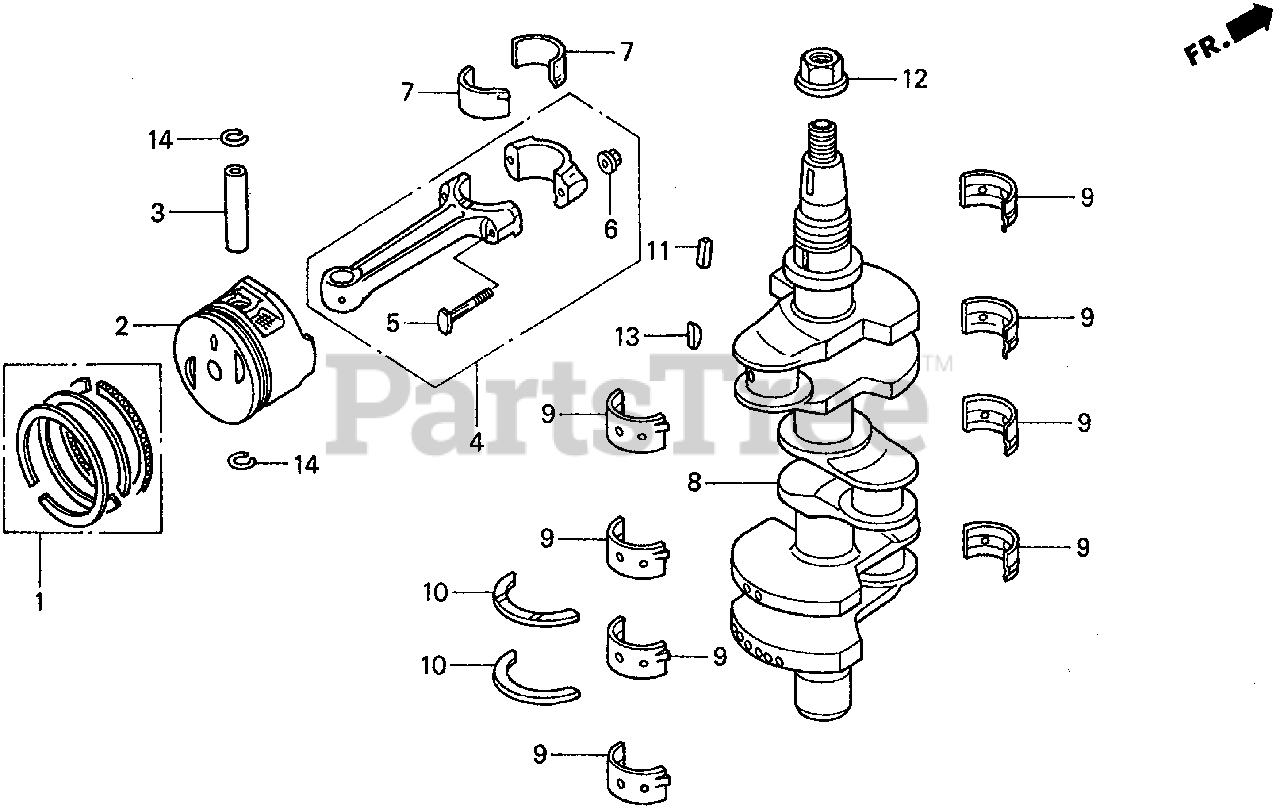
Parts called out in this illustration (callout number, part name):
1	RING SET, PISTON
1	RING SET, PISTON (OS 0.25)
2	PISTON (OS 0.25)
3	PIN, PISTON
4	ROD SET, CONNECTING
5	BOLT, CONNECTING ROD
6	NUT, CONNECTING ROD
7	BEARING A, CONNECTING ROD (BLACK)
7	BEARING B, CONNECTING ROD (BROWN)
7	BEARING C, CONNECTING ROD (GREEN)
7	BEARING D, CONNECTING ROD (YELLOW)
7	BEARING E, CONNECTING ROD (RED)
8	CRANKSHAFT
9	BEARING A, MAIN (17MM GREEN)
9	BEARING B, MAIN (17MM YELLOW)
9	BEARING C, MAIN (17MM PINK)
9	BEARING D, MAIN (RED)
10	WASHER, THRUST
11	KEY, SPECIAL WOODRUFF (25X18)
12	NUT, SPECIAL (16MM)
13	KEY, SPECIAL (16X15)
14	CLIP, PISTON PIN (14MM)
